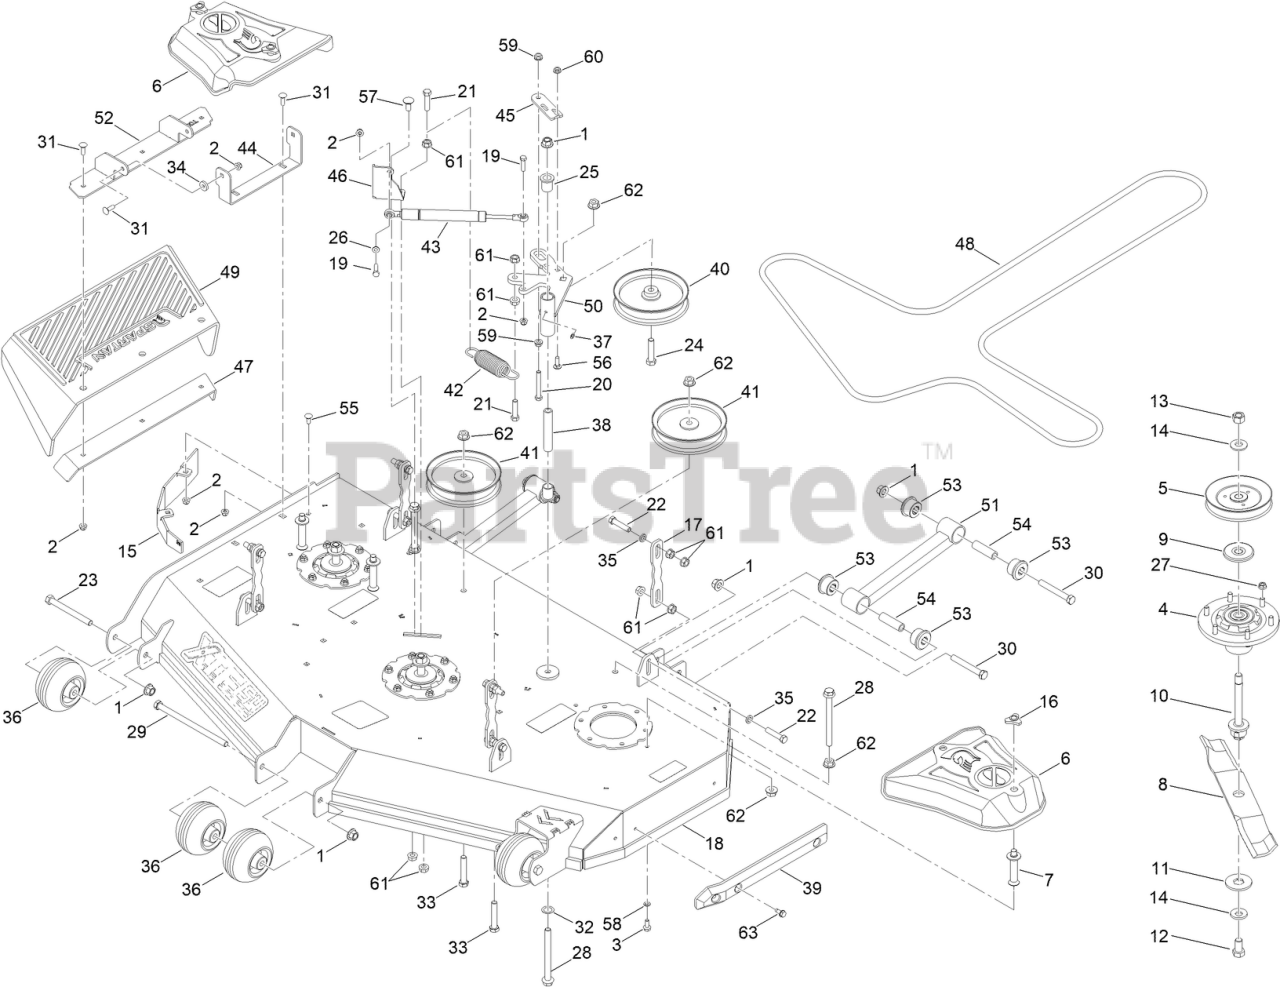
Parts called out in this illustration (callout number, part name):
1	NUT-LOCK
2	NUT-HF, NI
3	SCREW-HHF
4	SPINDLE ASM 5IN DECK
5	PULLEY
6	COVER BELT
7	PIN-BELT COVER
8	BLADE-ROTARY
9	GUARD-BEARING TOP 0.673IN
10	SHAFT - SPINDLE
11	WASHER-HEX
12	M16X1.5-30MM C10.9 HEX BOLT
13	M16X1.5 C8.8 HEX NUT
14	M16 SPRING WASHER (39MMOD/ 3.9MM THK)
15	BAFFLE-WIPER 54 PAINTED
16	NUT-KNOB
17	HANGER-DECK PAINTED GREY
18	ASM-DECK W/ DECALS
19	SCREW-HH
20	SCREW-HH
21	SCREW-HH
22	SCREW-HH
23	SCREW-HH
24	SCREW-HH
25	3/4IN ID X15/16IN OD X 1-1/8IN FLNG BUSH
26	.312IDX.625ODX.062 THK THRUST BRG OI BRZ
28	1/2-13 X 5-1/2 HEX FLANGE BOLT GR 8 ZY
29	1/2-13 X 8-1/2 HEX C/S GR 2 ZINC YELLOW
30	1/2-13 X 3-3/4 HEX C/S (GR.5) ZC/YEL
31	5/16-18 X 1 CARRIAGE BOLT GR 8 YZ
32	.767IDX1.125ODX.016 THK TRIP WV WASHER
33	1/2-13 X 2-3/4 HEX FLANGE BOLT (GR.8) YZ
34	.312 ID X .875OD X .1875 THK F/W NYL
35	.443 ID X .749 OD X .125 THK NYLON BLACK
36	MWR ANTI-SCALP WHL W/O GREASE FITTING
37	1/4IN DRIVE TYPE GREASE FITTING YZ
38	MWR INNER IDLER SPACER
39	MWR NYLON DECK GUARD
40	6-3/4IN IDLER PULLEY 7/16IN SPACER ASM
41	6-3/4IN IDLER PULLEY 15/16IN SPACER ASSY
42	MWR DECK SPRING
43	IDLER GAS SPRING
44	MWR CHUTE MTG BRKT PAINTED
45	DECK IDLER PULLEY BELT RETNR BRKT PAINT
46	DECK BELT IDLER DAMPER MTG BRKT PAINTED
47	RZ MWR DECK CHUTE HNGE BACKR BRKT PAINT
48	54 DECK BELT
49	RZ MWR RUBBER DISCHARGE CHUTE
50	MWR DECK IDLER PULLEY ARM ASSY PAINT
51	RZ MWR DECK STABILIZER ASSY PAINTED
52	2020 RZ MWR DECK CHUTE HINGE ASSY PAINT
53	RED A80 SUSP BUSHING
54	UTV A-ARM BUSHING SLEEVE
55	BOLT-CARR
56	BOLT-CARR
57	SCREW-CARR
58	WASHER-LOCK
59	NUT-HHF, WHIZ
60	NUT-HF
61	NUT-HF
62	NUT-HHF
63	SCREW-HWH, THREAD CUT
